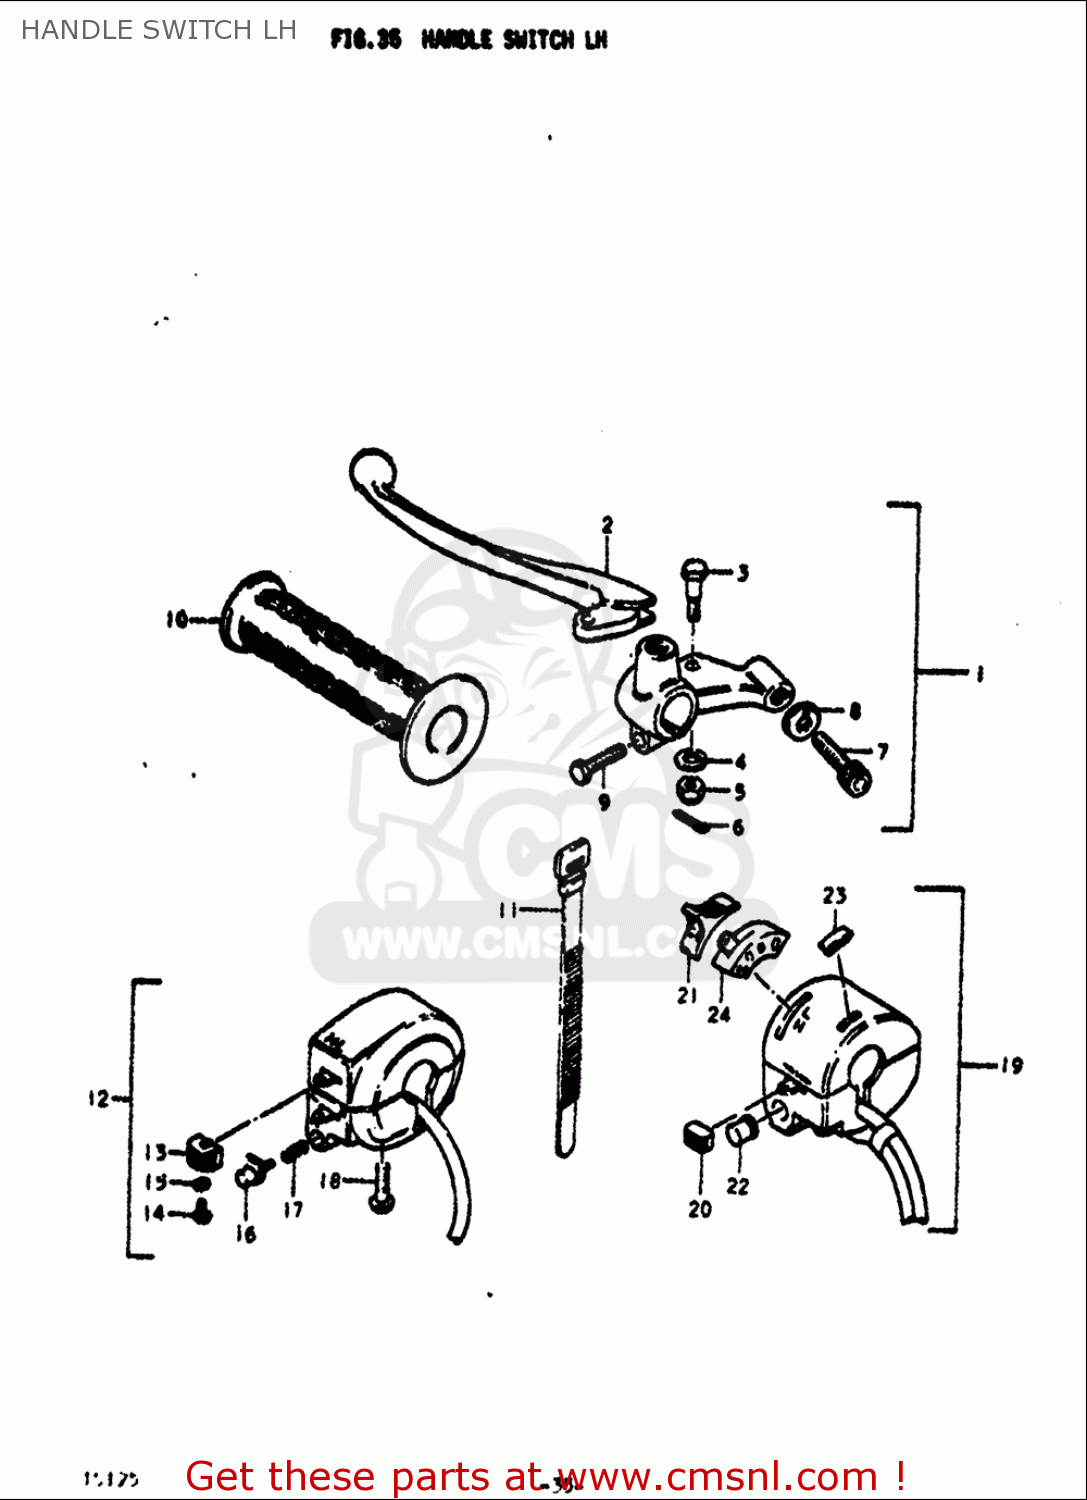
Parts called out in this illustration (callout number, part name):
2	LEVER,CLUTCH
3	BOLT,LEVER PIVOT
4	WASHER,LOCK
5	NUT,LEVER FITTNG
6	PIN 16X20
7	ADJUSTER,CABLE
8	NUT,CABLE ADJUSTER
9	BOLT
10	GRIP
11	CLAMP(L:120)
13	KNOB,HANDLE SWITCH,UPPER
14	SCREW
15	WASHER,LOCK
16	BUTTON,HORN
17	SPRING,BUTTON
18	SCREW(5X27)
20	KNOB,HANDLE SWITCH
22	BUTTON, HORN
